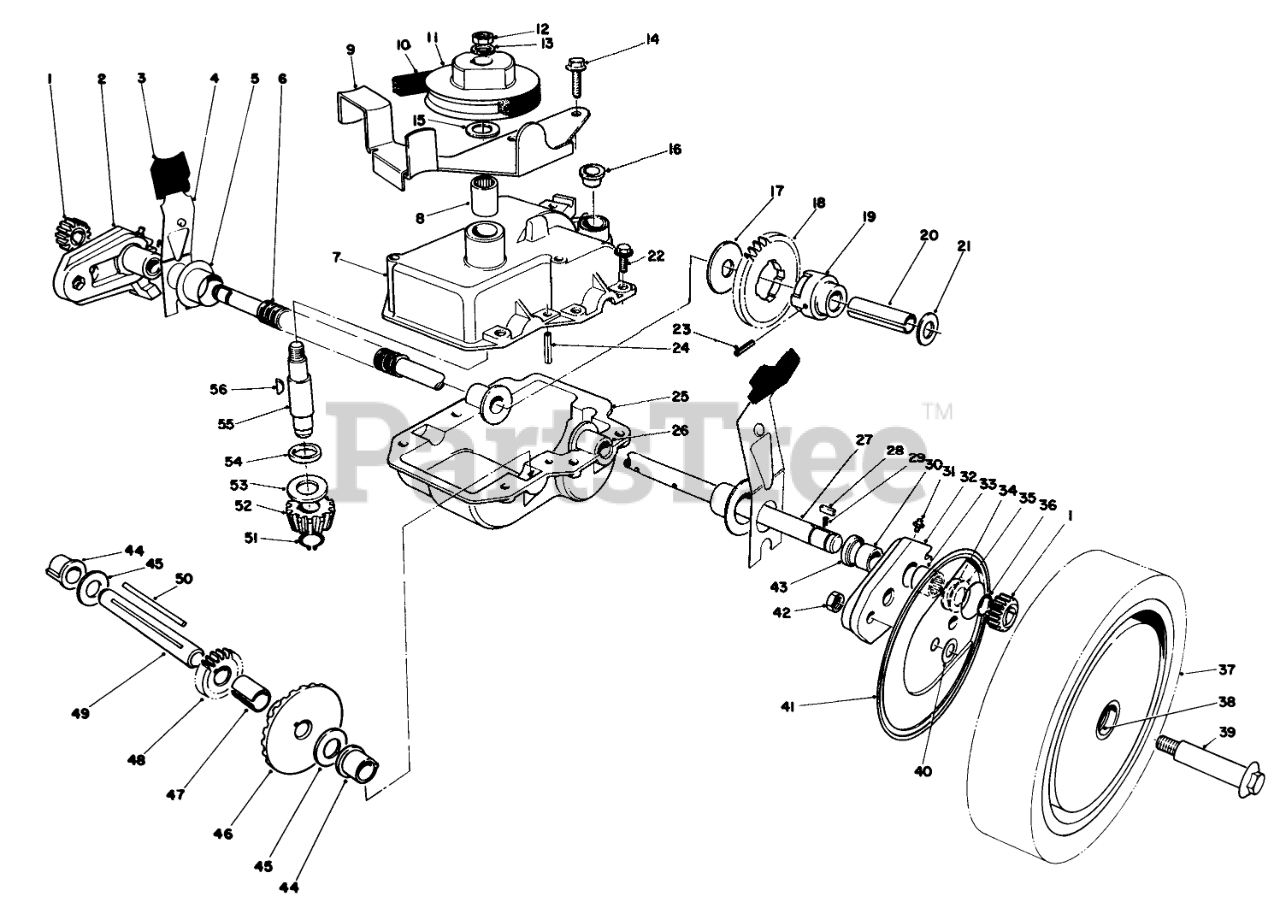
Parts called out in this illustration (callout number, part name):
1	GEAR-PINION
2	PIVOT ARM ASM RH
3	KNOB-ARM
4	SPRING ARM ASM SP
5	CAP-END
6	CONDUIT-CONVOLUTED, SPLIT
7	Case-Upper
8	BEARING
9	BELT GUIDE BRKTB
10	V-BELT
11	PULLEY
12	NUT-HEX
13	Washer
14	SCREW
15	WASHER-THRUST
16	Caplug
17	WASHER
18	GEAR-42T
19	DRIVE ADAPTER
20	Spacer-Output Shaft
21	Washer
22	SCREW-HWHTF
23	COIL PIN.156 X 1.125
24	ROLL PIN 3/16 X 1 IN
25	LOWER GEAR CASE CAST
26	Bushing-Output Shaft
27	Output Shaft
28	KEY RECTANGULAR
29	SPRING-COMPRESSION
30	BUSHING
31	FITTING-GREASE
32	Pivot Arm Assembly-L.H. (Incl. Ref. #30, 31, 33 & 43)
33	BEARING-ROLLER
34	INNER THRUST WASHER
35	WASHER-THRUST, OUTER
36	RING-RETAINING
37	Wheel, Tire & Gear Assembly (Incl. Ref. #38)
38	BUSHING
39	WHEEL BOLT
40	WASHER
41	WHEEL COVER
42	Nut
43	SEAL-OIL
44	BUSHING
45	WASHER-THRUST
46	BEVEL GEAR
47	Spacer-Short Shaft
48	GEAR-14T
49	INTERMEDIATE SHAFT
50	Key Square
51	RING-RETAINING
52	PINION-BEVEL
53	WASHER-THRUST
55	INPUT SHAFT
56	KEY-WOODRUFF
